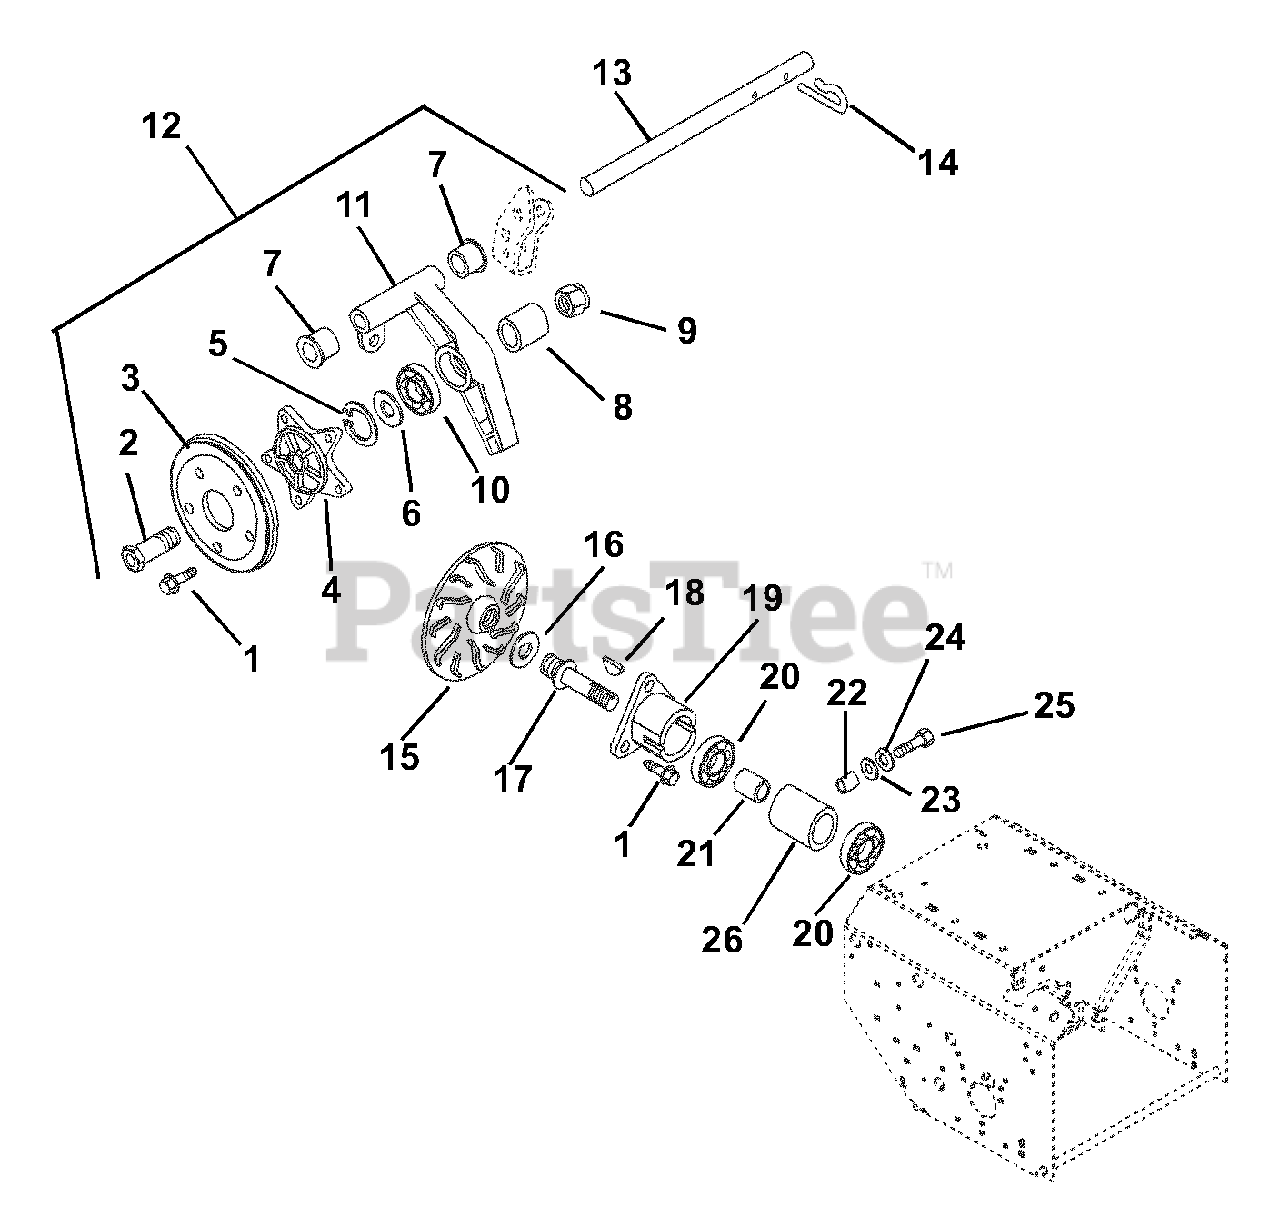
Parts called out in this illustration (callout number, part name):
1	Screw, Tapping .31-18 x .50
2	Spindle Hub
3	Friction Disc
4	Disc Hub
5	Ring, Retaining Internal 1.75 x .062
6	Washer, Flat Steel .88 x 1.25 x .062
7	Bushing, Flange .63 x .750 x .50 x .88
8	Bushing, Sleeve .88 x 1.25 x .53
9	Nut, Locking Nylon .88-14
10	Bearing, Ball .88 x 1.75 x .50
11	Carrier
12	Friction Wheel Assembly
13	Carrier Shaft
14	Pin, Spring Clip
15	Drive Plate
16	Drive Disc Spacer 1.30 x .76 x .19
18	Key, Feather .125 x .50 x .194
19	Housing Mount
20	Bearing .63 x 1.38 x .43
21	Bearing Spacer
23	Washer, Flat Steel .34 x .69 x .065
24	Washer, Lock .312 x .097
25	Bolt, Hex .31-18 x 1.00 Grade 5
26	Spindle Housing
